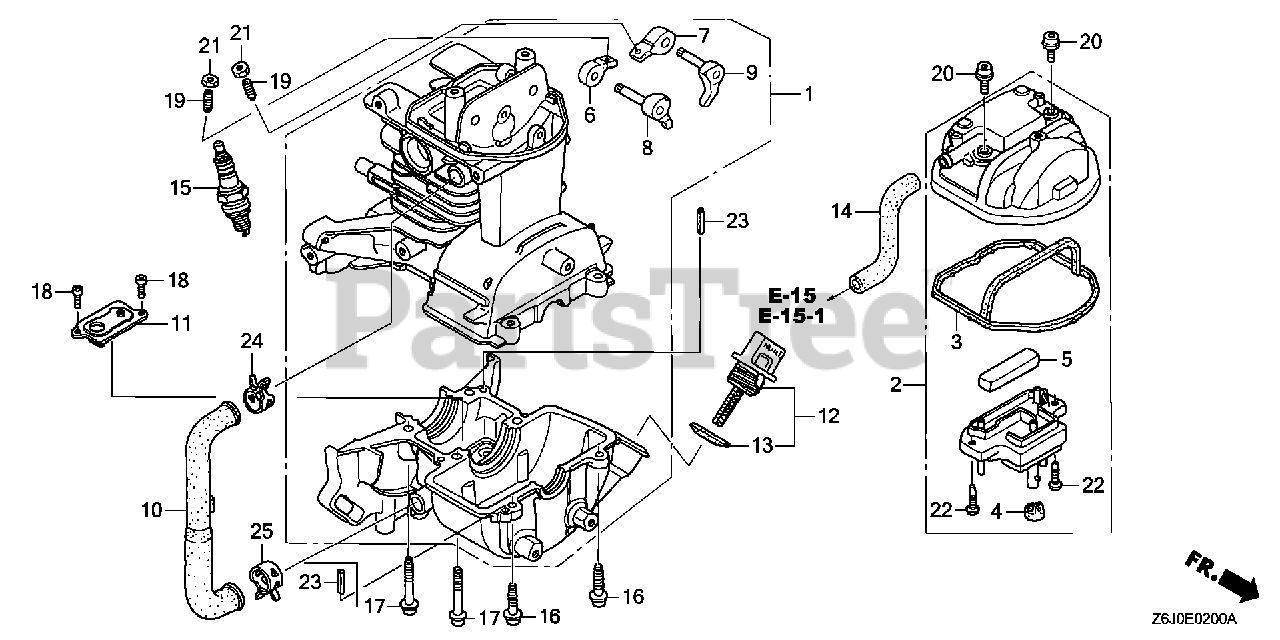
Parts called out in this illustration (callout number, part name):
1	CRANKCASE SET
2	COVER, CYLINDER HEAD
3	SEAL, HEAD COVER
4	GROMMET, HEAD COVER
5	FILTER, BREATHER
6	ARM, IN. VALVE ROCKER
7	ARM, EX. VALVE ROCKER
8	LIFTER, IN. VALVE
9	LIFTER, EX. VALVE
11	PLATE ASSY., OIL OUTLET VALVE
12	CAP ASSY., OIL FILLER
13	GASKET, OIL FILLER CAP
14	TUBE, BREATHER
15	SPARK PLUG (CMR4H) (NGK)
15	SPARK PLUG (CMR5H) (NGK)
15	SPARK PLUG (CMR6H) (NGK)
16	BOLT, SOCKET (5X20)
17	BOLT, SOCKET (5X30)
17	BOLT, SOCKET (5X32)
18	SCREW, PAN (4X8)
19	SCREW, TAPPET ADJUSTING
20	BOLT, SOCKET (5X12)
21	NUT, TAPPET ADJUSTING
22	SCREW, TAPPING (4X12)
23	PIN, SPRING (4X10)
24	CLAMP, TUBE (D12)
25	CLAMP, TUBE (D13)
